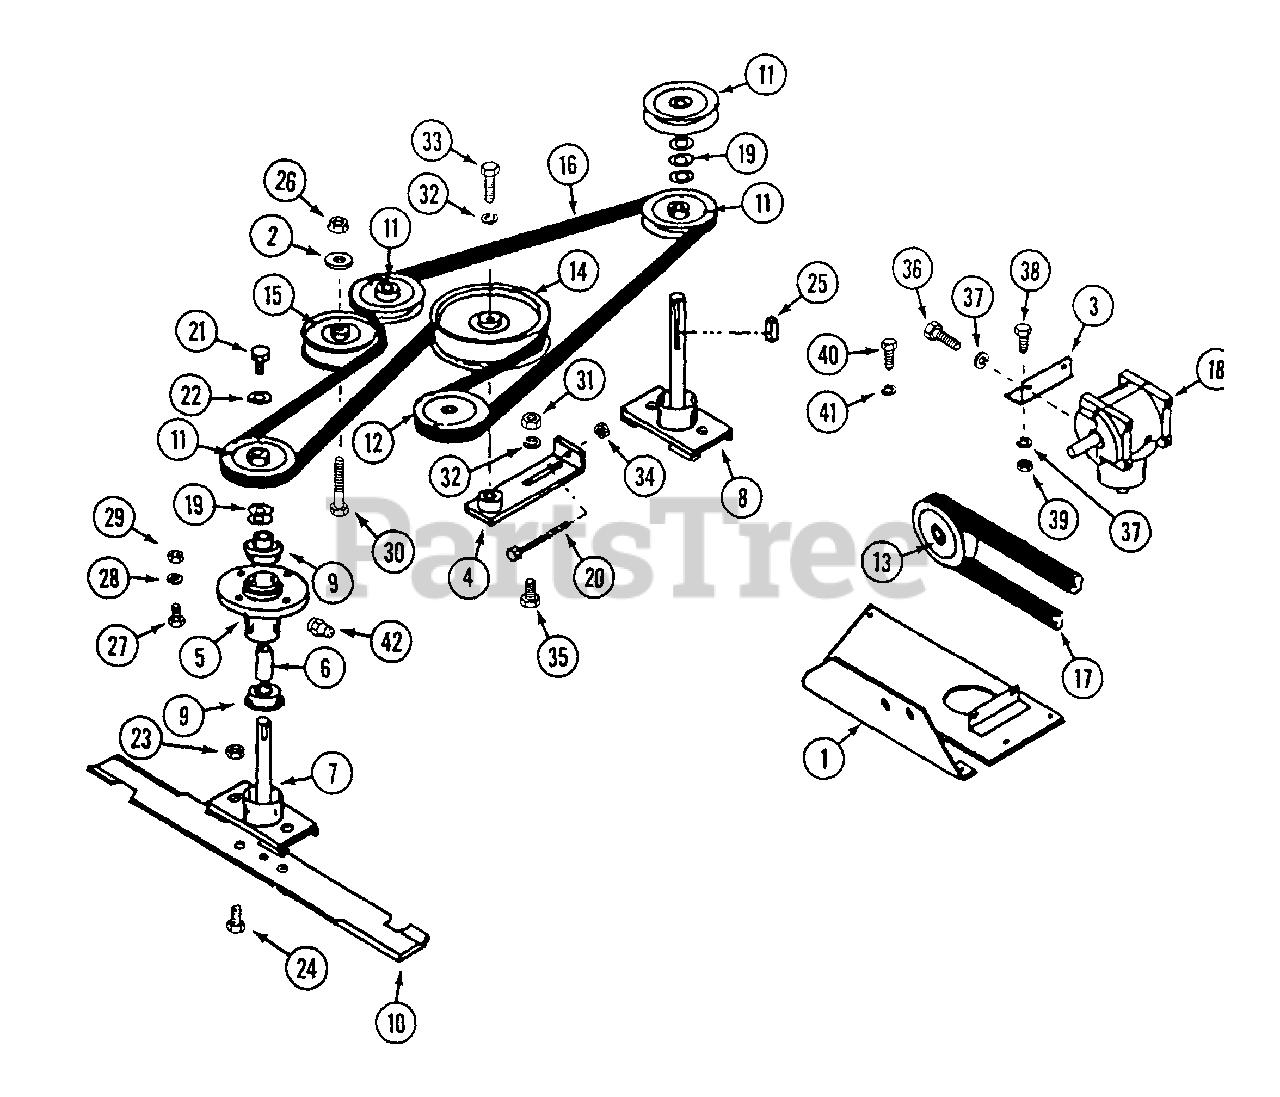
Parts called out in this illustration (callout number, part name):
1	MOUNT - gear box
2	WASHER - 3/8"
3	ANGLE - gear box mount
4	TIGHTENER - belt
5	HOUSING ASSEMBLY - spindle
5	HOUSING - spindle
6	SPACER - spindle
7	SHAFT - spindle, short
8	SHAFT - spindle, long
9	BEARING - spindle
10	BLADE - mower
11	PULLEY - spindle
12	PULLEY - gear box output
13	PULLEY - gear box input
14	PULLEY - idler, large
15	PULLEY - idler, small
18	GEAR BOX - angle drive
19	SPACER - washer
20	BOLT - 1/4" - 20 x 4"
21	BOLT - 3/8" - 24 x 1-1/4"
22	WASHER - 3/8" - 10 ga.
23	NUT - lock 3/8" - 16
24	BOLT - 3/8" - 16 x 1"
25	KEY - 3/16" x 1"
26	NUT - 3/8" flange lock
27	BOLT - 7/16" - 14 x 1-1/4"
28	LOCKWASHER - 7/16"
29	NUT - 7/16" - 14
30	BOLT - 3/8" - 16 x 2-1/4"
31	NUT - 3/8"
32	LOCKWASHER - 3/8"
33	BOLT - 3/8" - 16 x 1-1/4"
34	NUT - 1/4" - 20 lock
35	BOLT - 3/8" - 16 x 1" carriage
36	BOLT - 5/16" - 18 x 3/4"
37	LOCKWASHER - 5/16"
38	BOLT - 5/16" - 18 x 3/4"
39	NUT - 5/16" - 18
40	BOLT - 1/4" - 20 x 1/2"
41	LOCKWASHER - 1/4"
42	FITTING - grease 1/4" - 28
